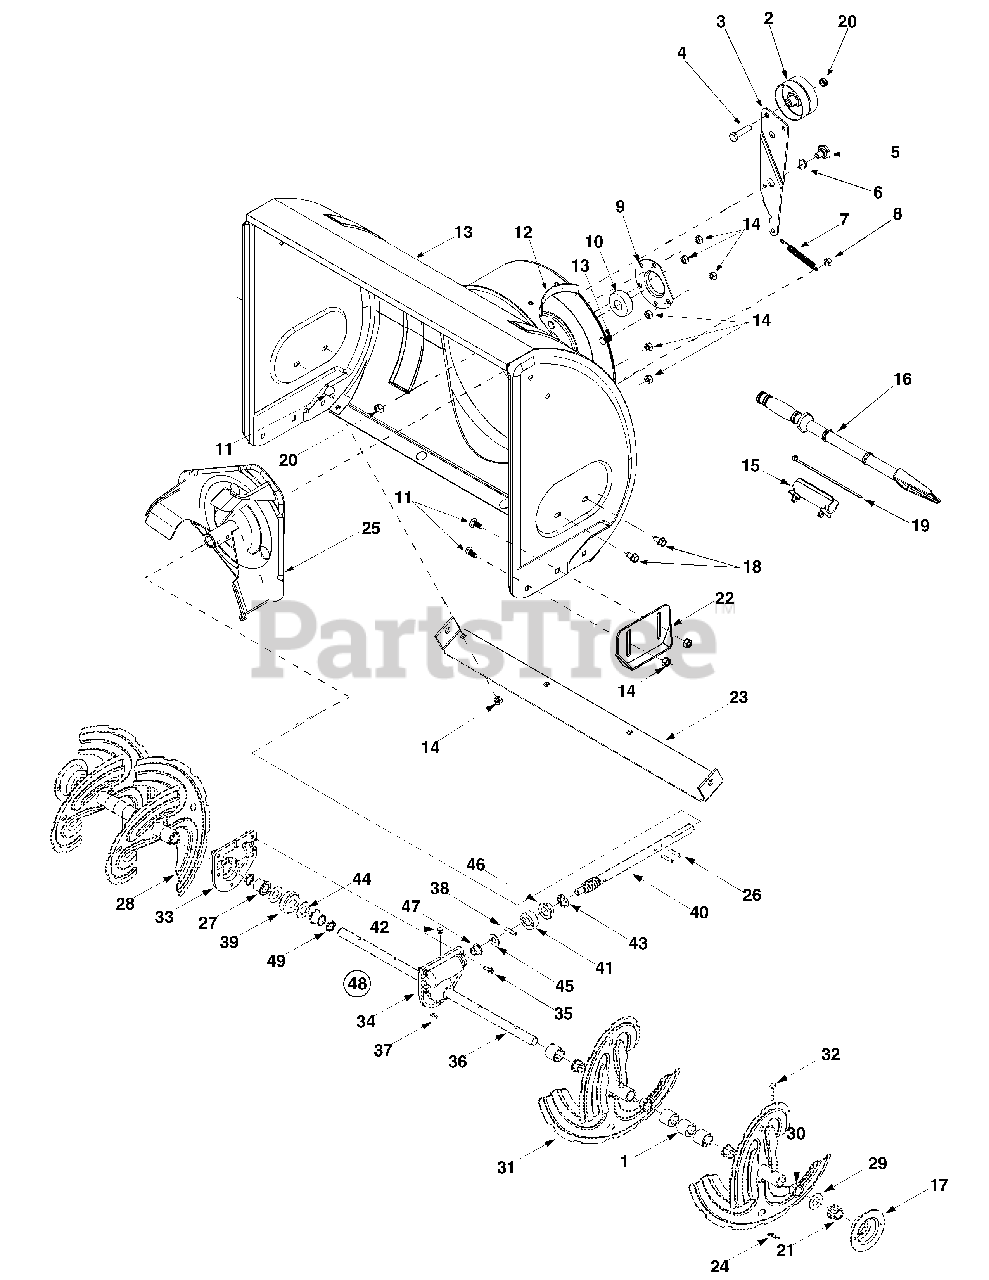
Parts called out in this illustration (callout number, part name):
1	Spacer, 1.25OD x.75ID x 1.00 Lg
2	Flat Idler
4	Hex Cap Screw 3/8-16 x 1.75
5	Shoulder Screw
6	Wave Washer
7	Extension Spring
8	Hex Nut 5/16-18
9	Housing
10	Ball Bearing
11	Carriage Bolt, 5/16-18 x.75
15	Clean-Out Tool Mount
16	Clean-Out Tool
18	Hex Screw 5/16-18 x.625
19	Cable Tie
20	Flange Lock Nut 3/8-16
21	Hex Flange Bearing
24	Bow Tie Cotter Pin
27	Flange Bearing
29	Flat Washer
30	Flange Bushing
32	Shear Pin,.25 x 1.50
33	RH Housing (Incl. Ref. # 27 & 49)
34	LH Housing (Incl. Ref. # 27 & 49)
35	Self Tapping Screw, 1/4-20 x.75
36	Auger Axle, 28"
37	Hi-Pro Key
38	Dowel Pin
39	Worm Gear, 20-tooth
40	Worm Shaft
41	Thrust Collar
42	Grease Plug
43	Grease Seal
44	Flat Washer
45	Flat Washer
46	Flange Bearing
47	Flange Bearing
48	Gearbox Assembly Complete,
49	Oil Seal
